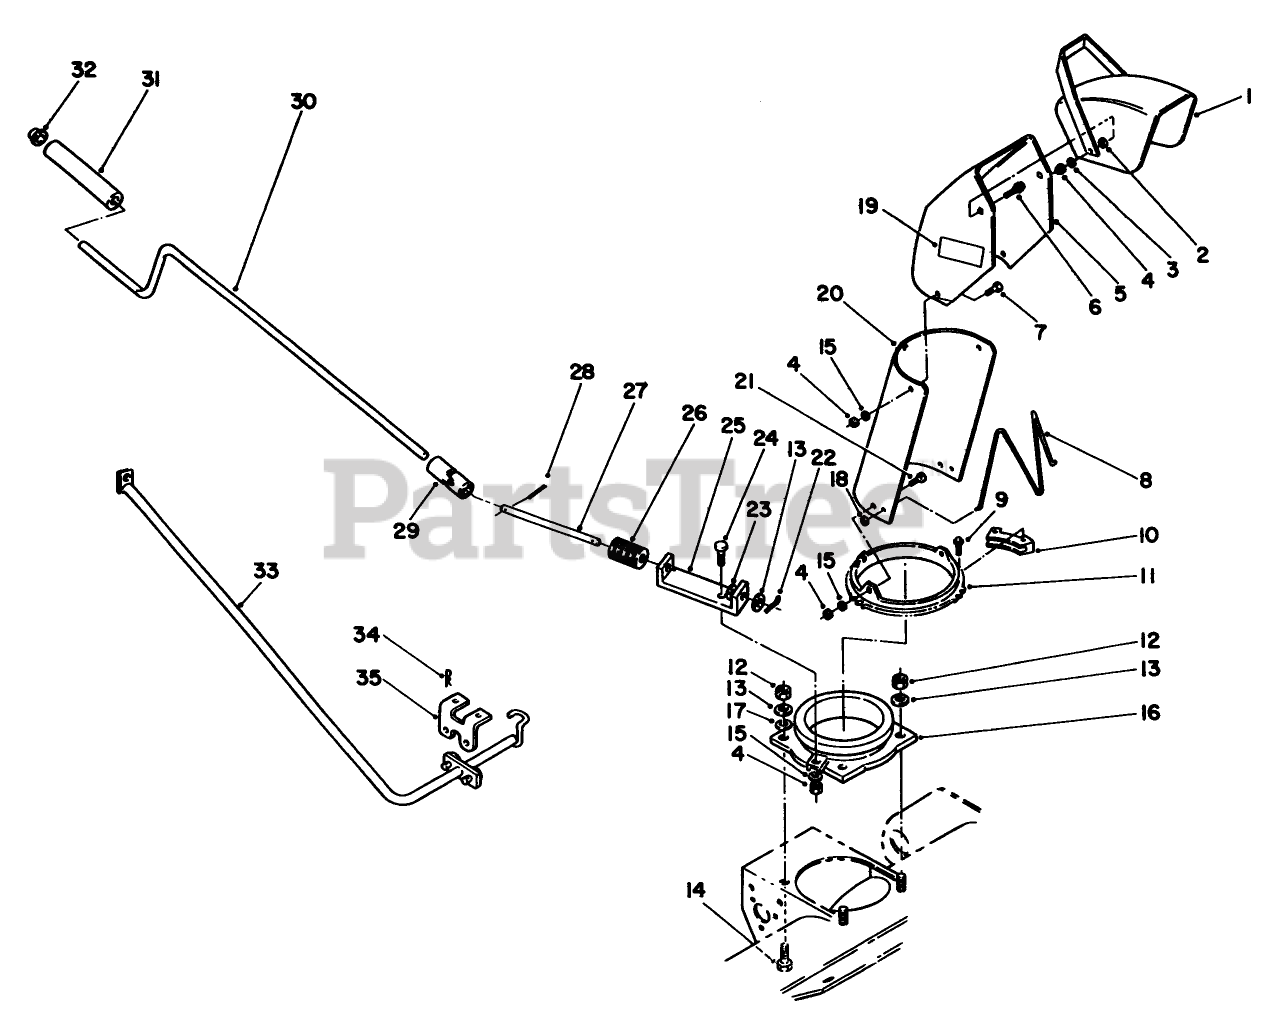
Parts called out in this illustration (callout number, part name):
1	Deflector
2	WASHER-RUBBER
3	WASHER-BELLEVILLE
4	NUT-LOCK, NI
5	Chute-Discharge (Incl. Ref. #19)
6	BOLT-CARR
7	SCREW-HH
8	WIRE-CHUTE
9	SCREW-SPECIAL
10	RETAINER-CHUTE
11	Ring-Swivel
12	NUT-LOCK, NI
13	WASHER-FLAT
14	SCREW-HH
15	WASHER-PLAIN
16	Adapter
17	WASHER
18	NUT-PUSH
19	DECAL DANGER
20	Chute-Extender
21	BOLT-CARR
22	PIN-COTTER
23	WASHER-SPRING
24	BOLT-CARR
25	Bracket-Worm
26	GEAR-WORM, CHUTE
28	PIN-SPRING
29	Universal
30	ROD-CHUTE CONTROL
31	GRIP-CONTROL, CHUTE
32	RETAINER-PUSH ON
33	WLDMT-CRANK SPT R
34	PIN-HAIR
35	Bracket
